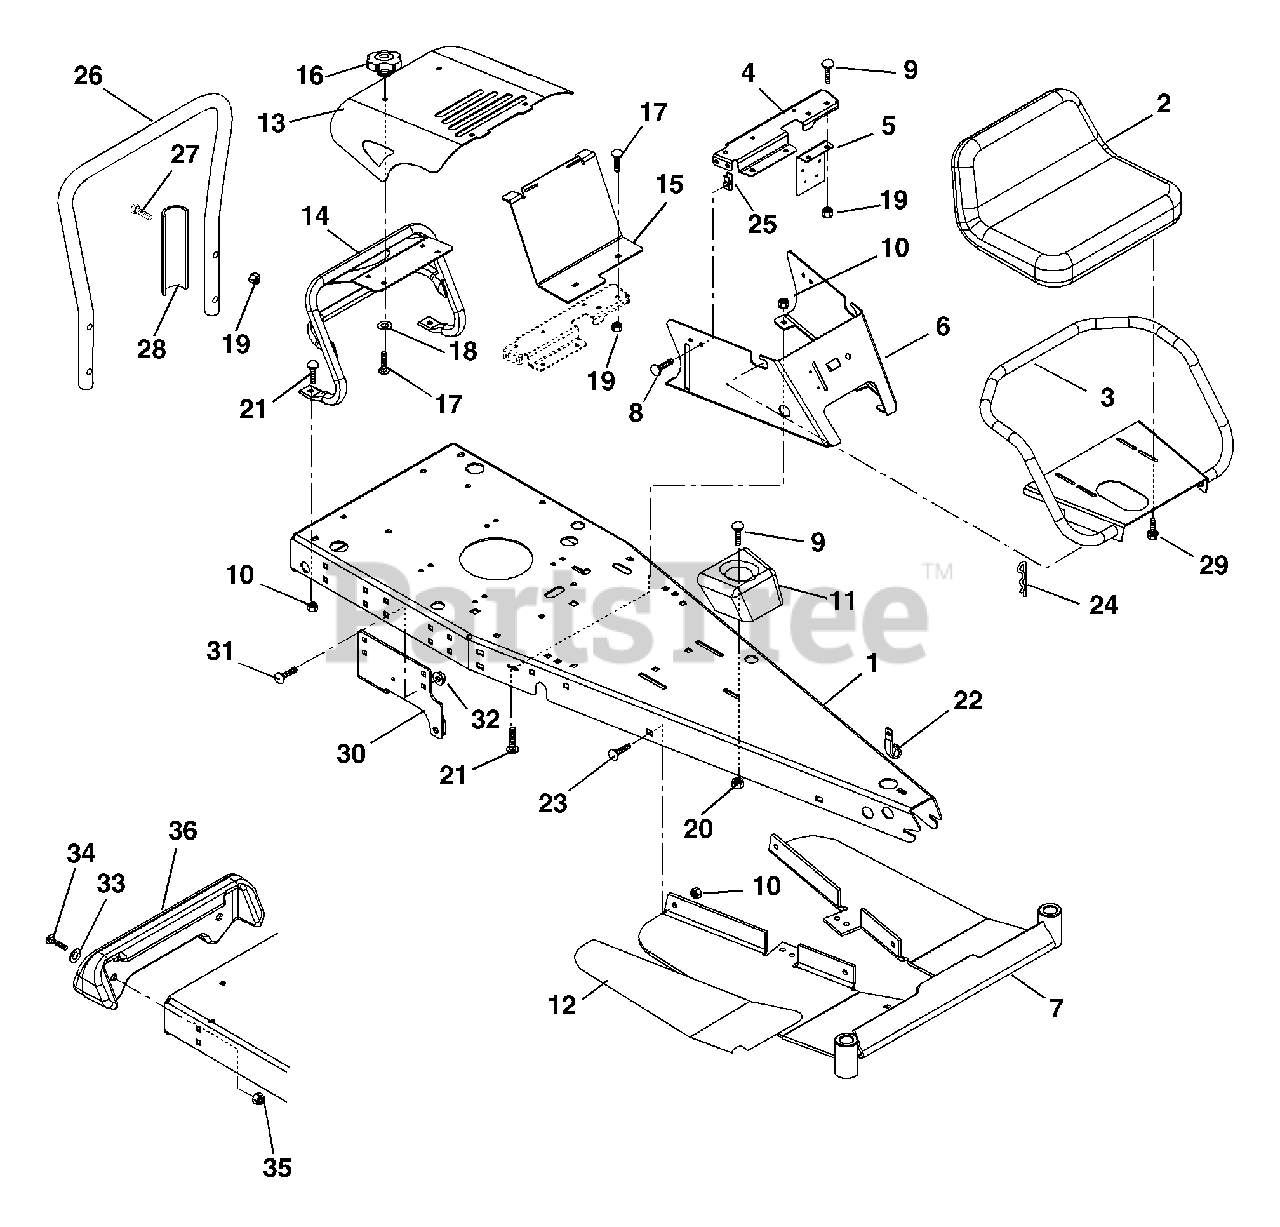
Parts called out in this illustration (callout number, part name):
1	FRAME,RER/SPORT-ZOOM
2	SEAT-LOW BACK TS2300
3	WLDMT, SEAT PLATE & ARMREST
4	REINFORCEMENT, SEAT SUPPORT
5	PANEL-SOLENOID MOUNTING
6	SEAT SUPPORT RER/MINI-Z-
7	WLDMT-FOOTREST RER/MINI-Z-
8	BLT-SERHFWH .25-20X.75 YWZC
9	BLT-RDHDSQNK .31-18X.75 G5BZ
10	NUT-LK-TOP-FLG .38-16 BLKZC
11	CUP HOLDER RER
12	GRIP, RER FOOTREST (LH)
12	GRIP, RER FOOTREST (RH)
13	ENGINE-HOOD ARIENS
14	WLDM'T TUBE
15	BRACKET-HOOD SUPPORT
16	KNOB-CLAMPING, .312-18 NYLOC
17	BLT-RDHDSQNK .31-18X1.0 SHTYZ
18	NUT-PUSH .312
19	NUT-LK-TOP-FLG .31-18 BLKZC
20	@NUT-SPNLK-FLG .312-18 YWZC
21	BLT-RDHDSQNK .38-16X.75 G5BZ
22	J-CLAMP
23	BLT-RDHDSQNK .38-16X1.00 G5BZ
24	PIN-HAIR-EXT .12X.31X2.37 YWZC
25	NUT-RTNR .25-20X.56
26	TUBE
27	@BLT-HEX .31-18X1.50 GR5 YWZC
28	BRACE
29	BLT-SERHFWH .31-18 X 1 YWZC
30	BRKT, TRANS (RH-WLDMNT)
30	BRKT, TRANS (LH-WLDMNT)
31	BLT-RDHDSQNK .38-16X.75 G5BZ
32	NUT-LK-TOP-FLG .38-16 BLKZC
33	@WSHR-FL-STL.438X1.00X.083 YWZ
34	@BLT-HEX .38-16X1.75 GR5 YWZC
35	NUT-LK-TOP-FLG .38-16 BLKZC
36	WEIGHT, SPORT-Z
